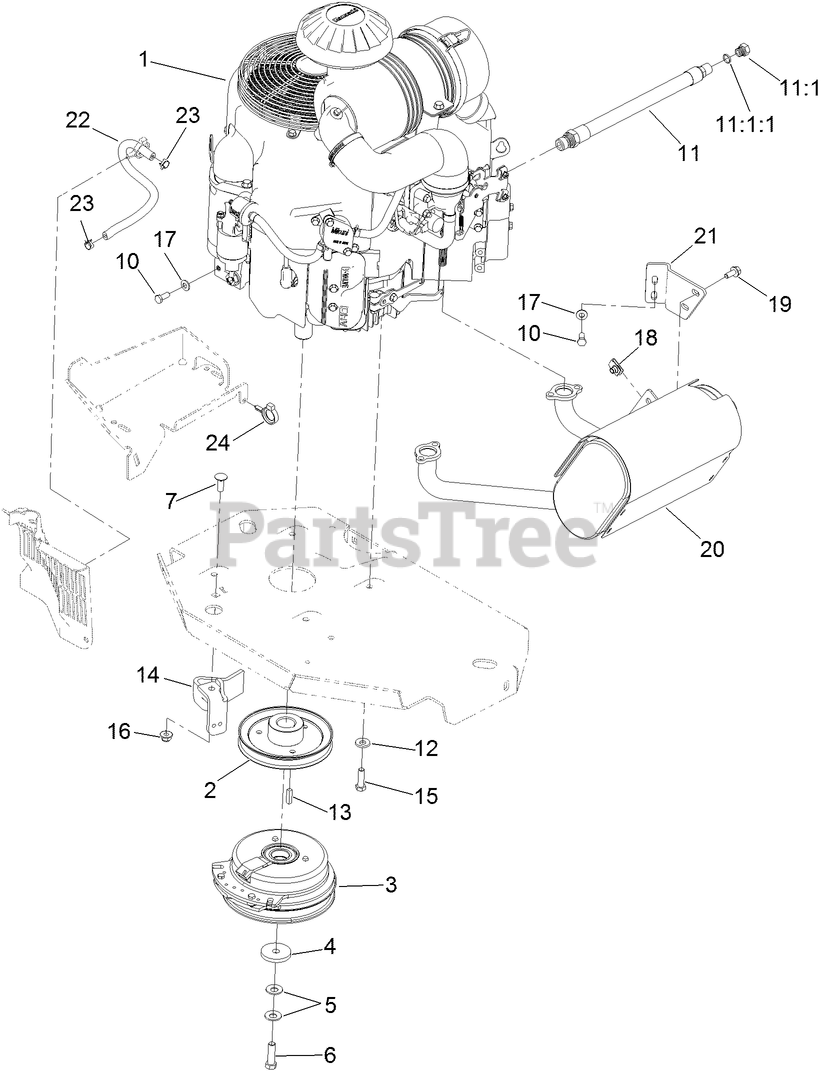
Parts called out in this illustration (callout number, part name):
2	SHEAVE
3	CLUTCH KIT
4	WASHER-CLUTCH
5	WASHER-SPRING
6	SCREW-HH, W/LOCTITE
7	SCREW-CARR
10	SCREW-HH
11	ENGINE OIL DRAIN HOSE ASM
11:1	PLUG-HH
11:1:1	O-RING
12	WASHER-BELLEVILLE
14	CLUTCH-ANCHOR
15	SCREW-HH
16	NUT-HF, NI
17	WASHER-SPRING
18	NUT-U
19	SCREW-HHF
20	MUFFLER
21	BRACKET-MUFFLER
22	HOSE-FUEL
23	CLAMP-HOSE
24	CLAMP-HOSE
